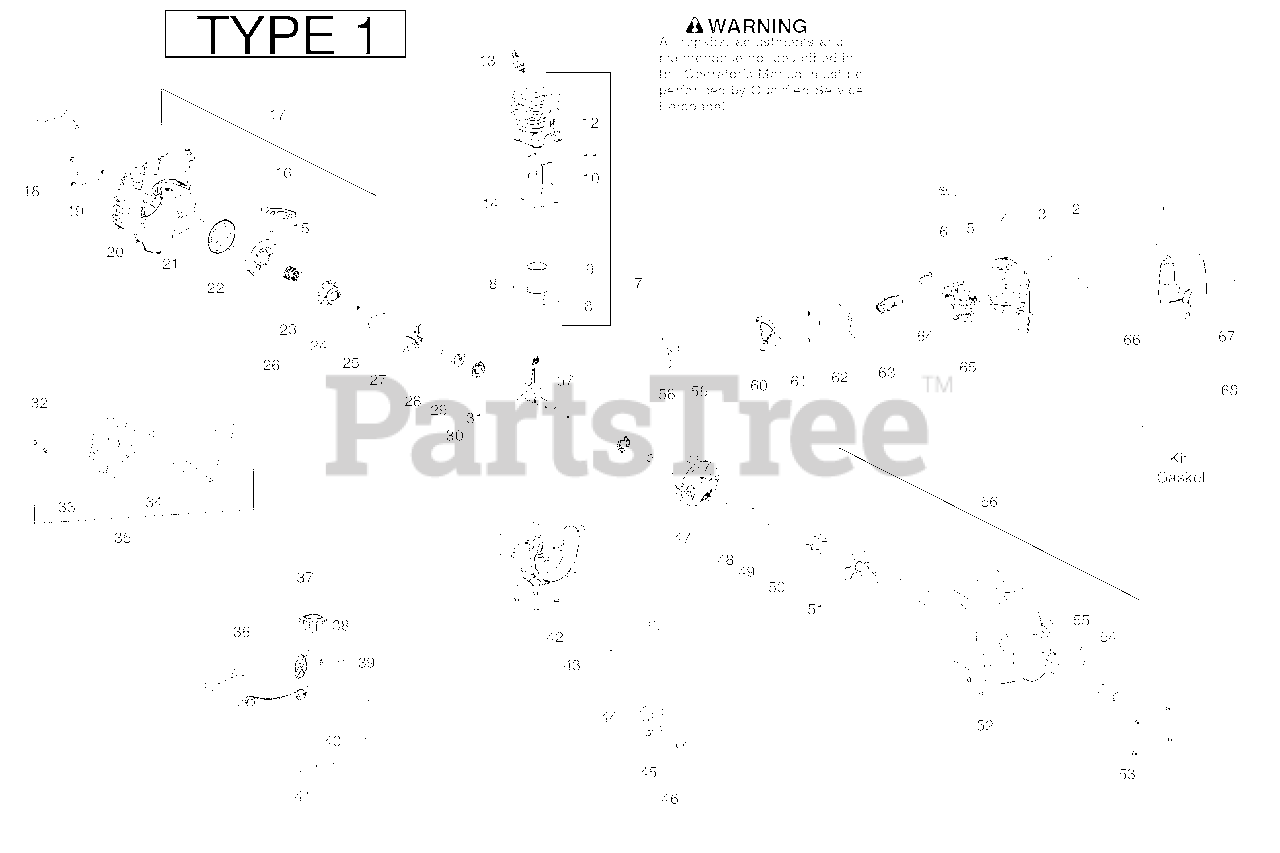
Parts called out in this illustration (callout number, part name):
1	Cover - Airbox
2	Nut - Carb. Screw
3	Screw 8-32
4	Base - Airbox
6	Assy - Purge Bulb
7	Kit - Piston/Cylinder
8	Retainer - Piston pin
9	Ring - Piston
10	Insert - Front Transfer Port
11	Insert - Rear Transfer Port
12	Cylinder - Machined
13	Spark Plug (RCJ- 6Y)
14	Seal - Cylinder (Kit)
15	Kit - Rope
16	Handle - Starter
17	Assy - Starter/Shroud
18	Screw M4 x 1.75
19	Screw m5x25mm
20	Assy - Starter Hsg. w/eyelet
22	Kit - Starter Spring
23	Spring - Starter Hub
24	Hub - Starter
25	Screw m6
26	Kit - Starter Pulley
27	Coupling - Starter
28	Assy - Starter Cup
29	Washer - Flat
30	Seal - Crankshaft (kit)
31	Bearing - Crankshaft
32	Bolt - Muffler
33	Kit - Spark Arrestor
34	Gasket - Muffler (kit)
35	Assy - Muffler
36	Screw - Tank Retainer
37	Assy - Fuel Cap w/ret.
38	Assy - Tank
39	Kit - Fuel line
40	Fitting - Fuel Line
41	Assy - Fuel Pickup
42	Screw - M5x25mm
43	Crankcase
44	Assy - Leadwire
45	Module - Ignition
46	Screw 8-32
47	Flywheel
49	Spacer - Flywheel
50	Washer - Clutch
51	Kit - Clutch Assy.
52	Screw 10-24 x 1"
53	Screw M5 x 25mm
54	Guide - Clutch Drum
55	Locknut 10-24
56	Assy - Fan Housing
57	Kit - Crankshaft Assy.
58	Gasket - Adapter/Cyl. (kit)
59	Bolt M5 x .80
60	Adaptor - Carburetor
61	Screw .20 x 32
62	Gasket - Carb./Adapter(kit)
63	Boot - Carb.
64	Lever - Choke
65	Carburetor (WTA-31)
66	Filter - Air
67	Bolt - Knob
68	Kit - Gasket
